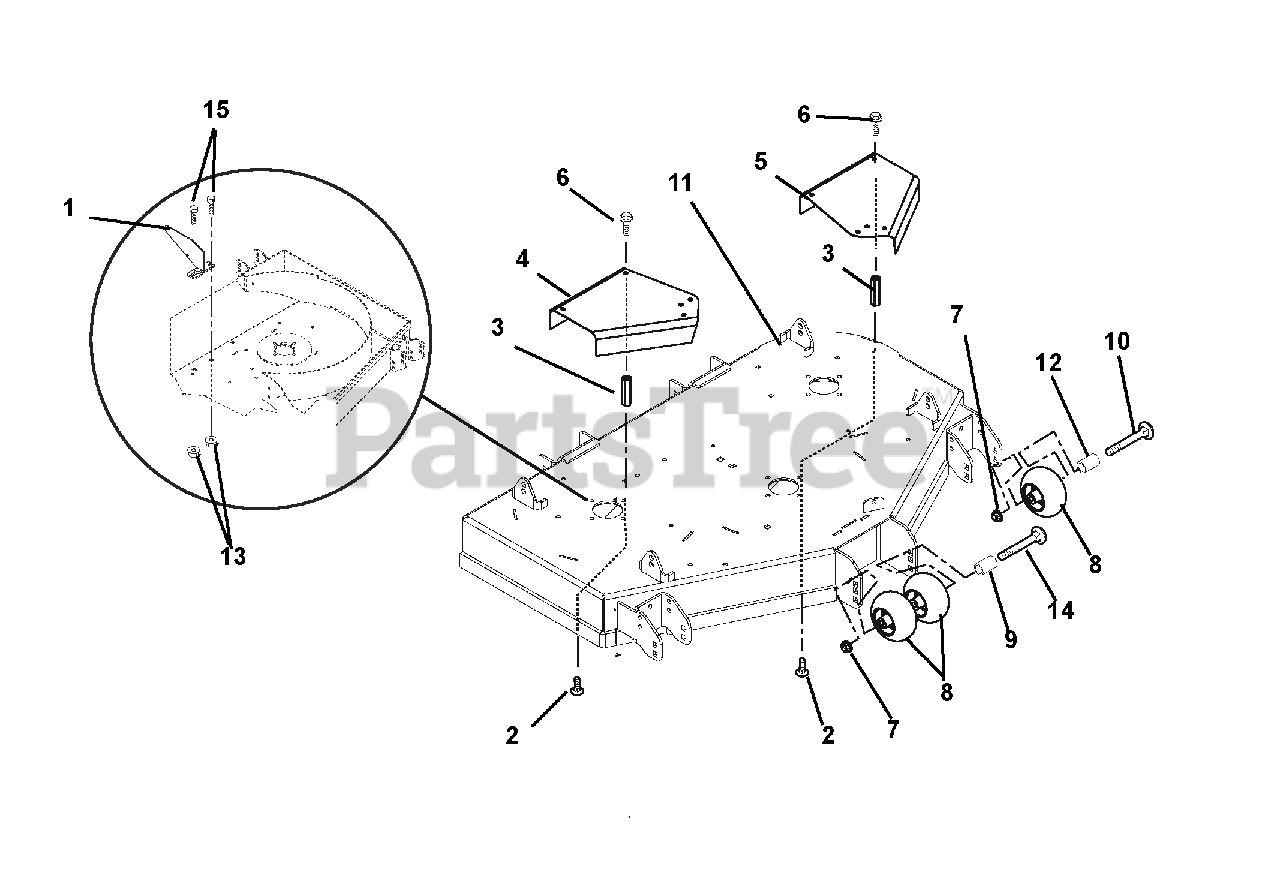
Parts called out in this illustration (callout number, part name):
1	REAR DISCH DEFLECT BFL WMT-RED
2	BLT,RDHDSQNK .31-18X.75 LOCTIT
3	NUT, COUPLING .31-18 X 3.00
4	44"RH SPINDLE SHEAVE GUARD-RED
5	44"-52" LH SPNDL SHV GUARD-RED
6	BOLT, SEMS .31-18 X .62
7	@NUT-LK-NYL-FLG .50-13 YWZC
8	WHEEL, ANTI SCALP
9	SPACER, .510X.625X6.50
10	BLT-RDHDSQNK .50-13X5.00 GR5YZ
11	XDZ44" REAR DISCH DECK WMT-RED
12	SPACER, .510X.625X3.35
13	@NUT-LK-NYL-FLG .38-16 YWZC
14	@BLT-RDHDSQNK .50-13X8.50 G5YZ
15	@BLT-RDHDSHSQNK.38-16X1.0 G5YZ
